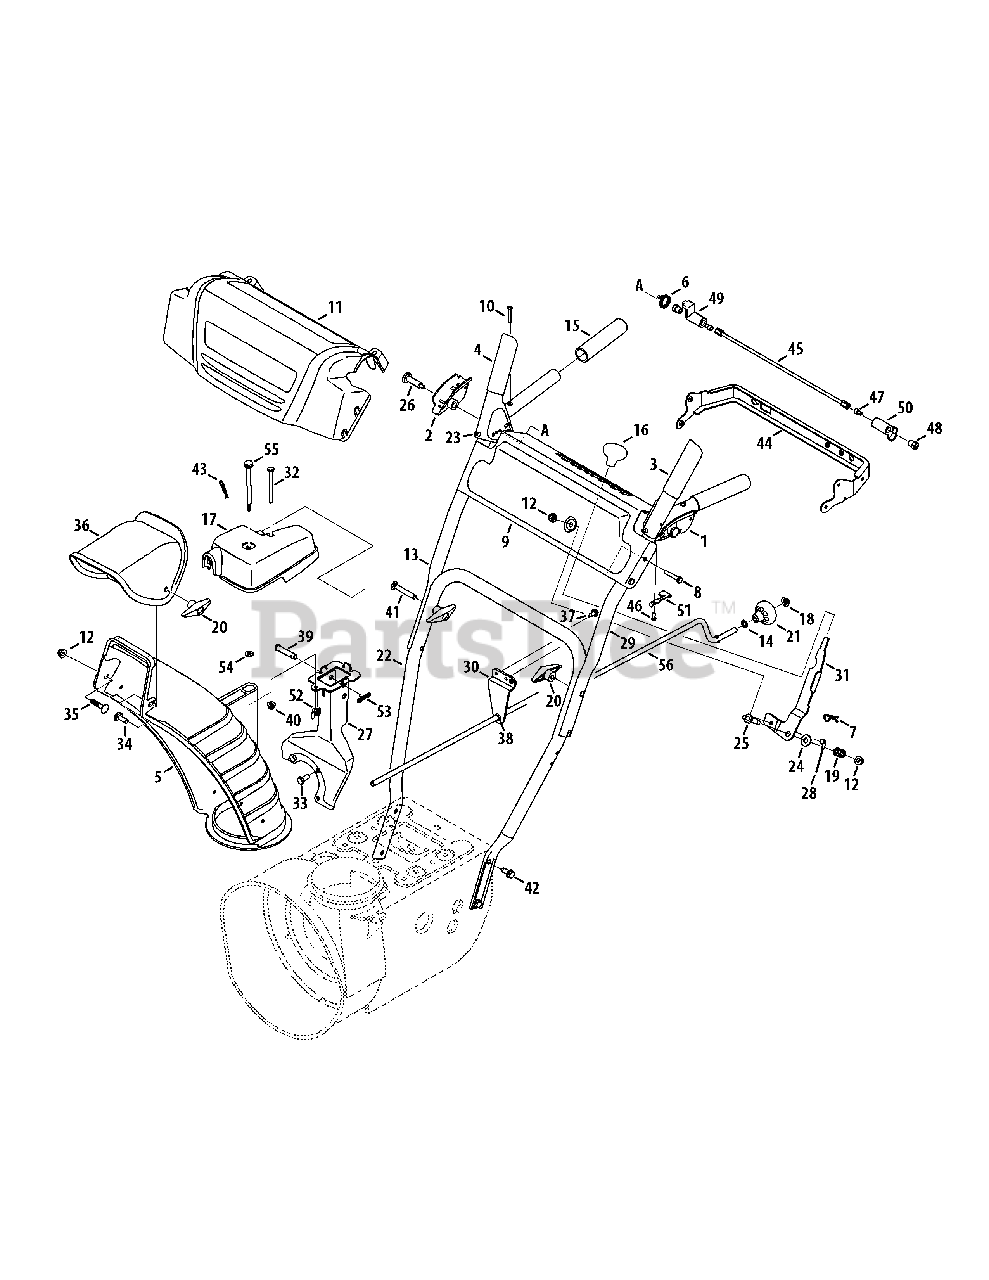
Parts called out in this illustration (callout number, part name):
1	Handle Assembly, Clutch Lock, LH
2	Handle Assembly, Clutch Lock, RH
3	Handle Ass’y, Engage, LH
4	Handle Ass’y, Engage, RH
5	Chute, Lower
6	Spring, Torsion, .8156 ID x .3038
7	Click Pin
8	Screw, 1/4-20 x 1.625
9	Panel, Handle, (no cutout)
10	Screw, Machine, #10-24, 1.375
11	Handle Panel Cover
12	Nut, Flange Lock, 5/16-18, Nylon
13	Handle, Upper, RH
14	Washer, Flat, .375 x .738 x .063
15	Grip, 1.0 ID x 5.0
16	Knob, Shift, Black
17	Gearbox Assembly
18	Cap, Push, 3/8 Rod
19	Spring, .39 x .60 x .88
20	Knob, 5/16-18, Black
21	Crank Knob
22	Handle, Lower
23	Bumper, Rubber, .62 OD x .22
24	Washer, Flat, .385 x .870 x .092
25	Bolt, Shoulder, 5/16-18 x 0.905
26	Screw, Shoulder, .43 x 1.3, 1/4-20
27	Bracket, Chute Support
28	Cable, Speed Selector
29	Handle, Upper, LH
30	Bracket, Rod
31	Shift Lever
32	Screw, 1/4-20 x 3.00
33	Screw, 5/16-24 x .750
34	Bolt, Carriage, 5/16-18, 1.0
35	Bolt, Carriage, 5/16-18, .750
36	Chute, Upper, w/ Label
37	Screw, 1/4-20 x .625
38	Bushing, Plastic, .380
39	Pin, Clevis
40	Nut, Flange Lock, 1/4-20
41	Screw, Carriage, 5/16-18, 2.25
42	Screw, 5/16-18, 2.25, Gr5
43	Pin, Cotter
44	Bracket, Panel
45	Rod, Pivot
46	Screw, #8-16 x .50
47	Screw, 1/4-20 x .50
48	Nut, Hex, 1/4-20
49	Plate, Lock
50	Cam, Clutch Lock
51	Spring, Clutch Lock
52	Nut, Wing
53	Bow-Tie Cotter Pin
54	Washer, Flat, .25 x .630 x .0515
55	Scr. Shldr. Flg., .312 x 3.5 x 1/4-20
56	Crank, Chute
